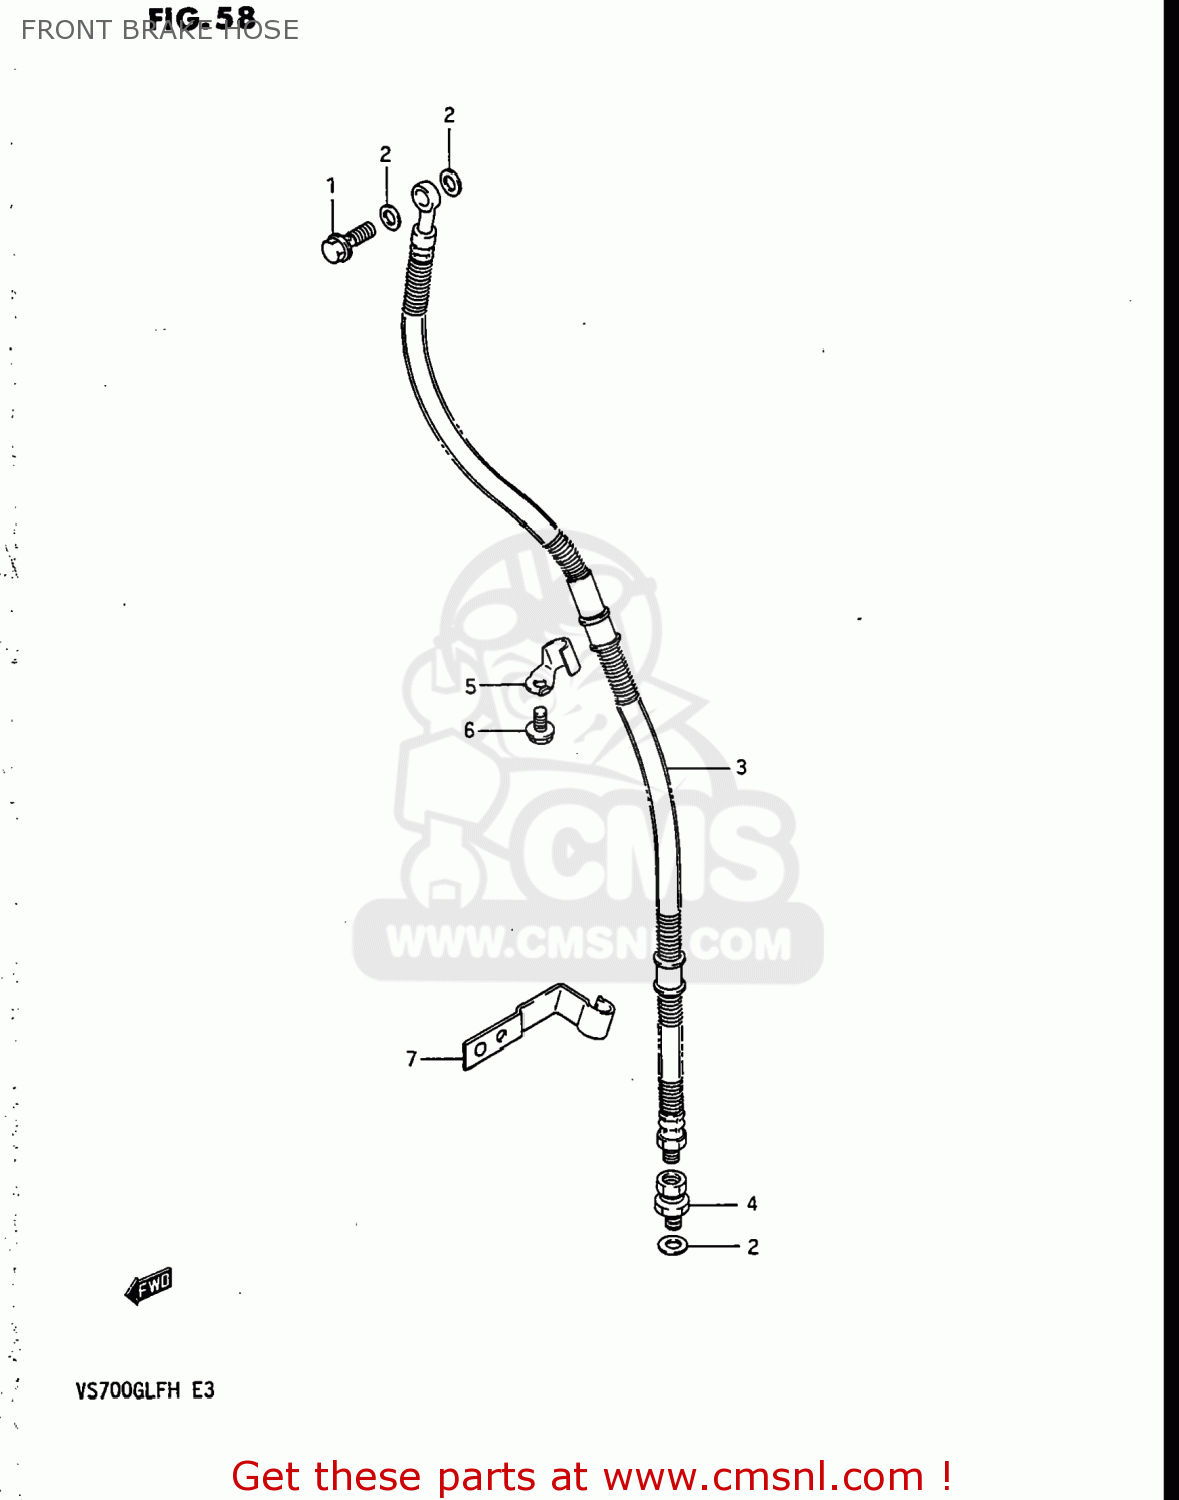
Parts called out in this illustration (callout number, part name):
1	BOLT UNION
2	WASHER(10X15X1.5)
3	HOSE,FRONT BRAKE
4	ADAPTER,BRAKE HOSE
5	GUIDE,BRAKE HOSE NO.1
6	BOLT
7	GUIDE,BRAKE HOSE NO.2
